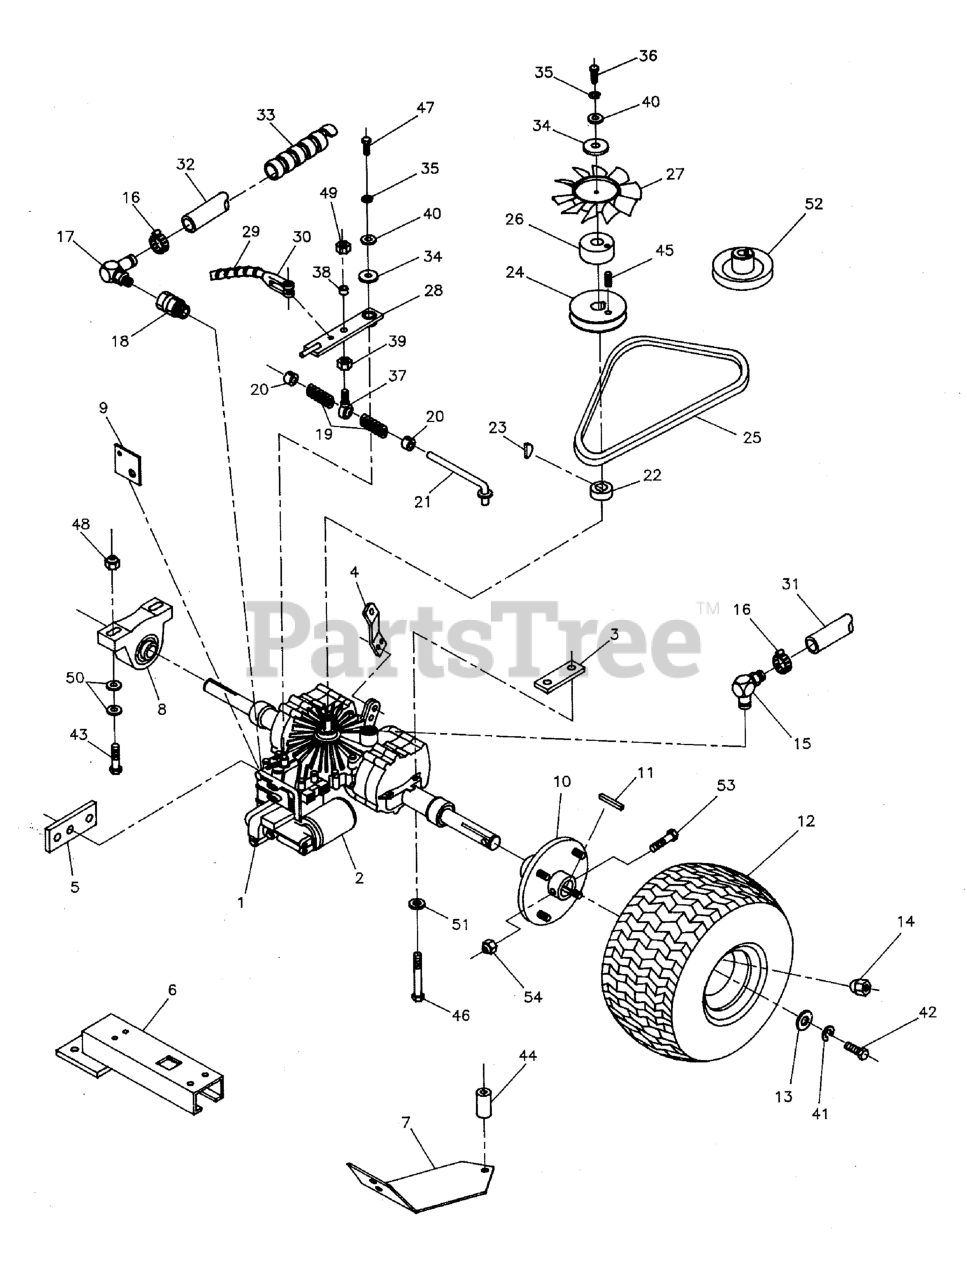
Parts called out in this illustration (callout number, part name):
1	Transmission
2	FILTER, Transmission Oil
3	Differential Spacer
4	BRAKE LEVER
5	BRACKET, Transmission Support
6	AXLE SUPPORT
7	Skid Plate
8	BEARING, PILLOW BLOCK, 1
9	DUMP VALVE LEVER
10	DRIVE HUB DETAIL
11	KEY, 1/4 SQ. X 2-1/2
11	Drive Axle Key
12	TIRE & WHEEL ASSEMBLY, 18 X 8.5 X 8
12	WHEEL & TIRE ASSEMBLY, 20 x 10 x 8, Complete
13	Retaining Spacer
14	LUG NUT, 1/2-20
15	FITTING, 90 Degrees 7/8" O-Ring
16	CLAMP, #10 Hose
17	FITTING, 90 Degrees 1/2" NPT
18	FITTING, 7/8" O-Ring Straight Swivel
19	SPRING, Compression
20	COLLAR, 5/16" Set
21	ROD, NEUTRAL SPRING WELDMENT
22	SPACER, .67 x 1.25 x .50
23	KEY, #61 Woodruff
24	Pulley 17mm Bore
25	BELT, A-Section
26	Fan Pulley Spacer
28	TRANSMISSION CONTROL ARM
29	CABLE, Speed Control
30	5/16" Rod End Clevis
31	Return Hose
32	Inlet Hose
33	Plastic Hose Coil
34	WASHER, 5/16" Fender
35	WASHER, 1/4 LOCK
36	BOLT, 1/4-20 x 1-3/4
37	BALL JOINT, 3/8-24 Male
38	SPACER, .38 x .50 x .27
39	NUT, 3/8-24 Hex
40	WASHER, 1/4 SAE
41	WASHER, 3/8" Lock
42	BOLT, 3/8-16 X 1-1/4" GD5 CZ
43	BOLT, 7-16-20 x 1-1/2
44	SPACER, .41 x 1.00 x 1.50
45	PIN, Roll, 3/16 x 1
46	BOLT, 3/8-16 X 3-1/2" GD5 CZ
47	BOLT, 1/4-20 x 1-1/2
48	NUT, 7/16-20 Hex Nylon Lock
49	NUT, 3/8-24 Hex Nylon Lock
50	WASHER, 7/16" SAE
51	WASHER, 3/8 SAE
52	PULLEY, Transmission Input
53	BOLT, 5/16-24 x 2" GD 8
54	NUT, 5/16-24 HEX NYLON LOCK
